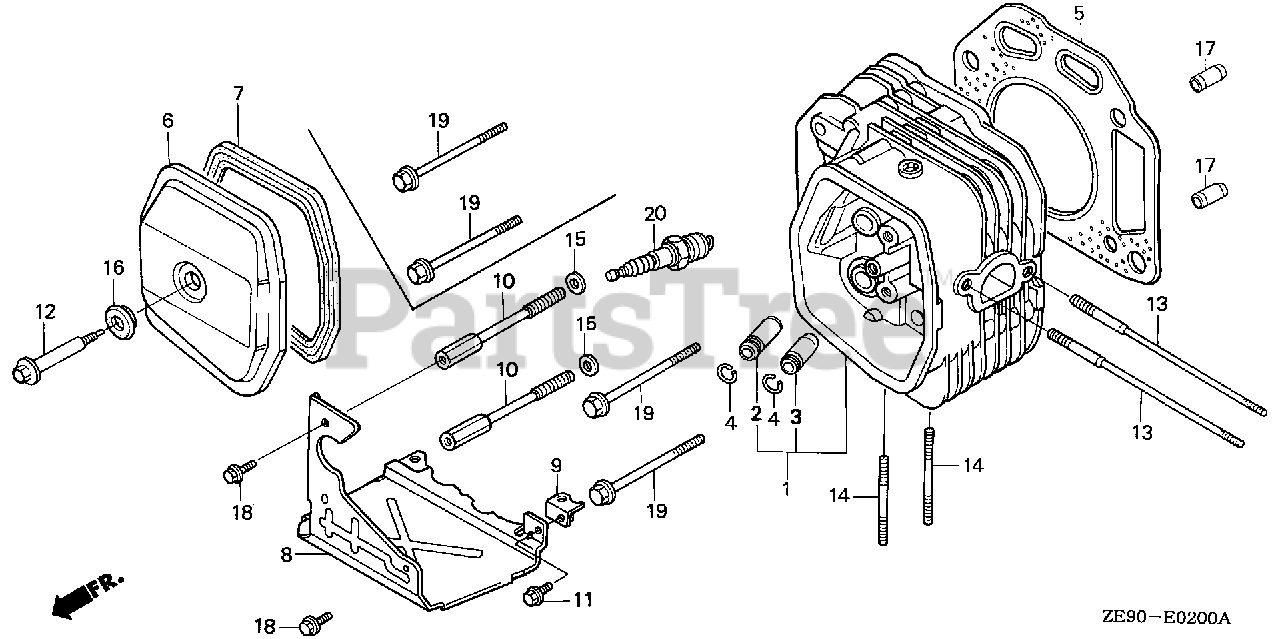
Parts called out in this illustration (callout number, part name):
1	CYLINDER HEAD
2	GUIDE, VALVE (OVER SIZE)
3	GUIDE, EX. VALVE (OVER SIZE)
4	CLIP, VALVE GUIDE
5	GASKET, CYLINDER HEAD
6	COVER, HEAD
7	GASKET, HEAD COVER
8	COVER (LOWER)
9	STAY, COVER (LOWER)
10	BOLT, SPECIAL HEAD COVER
11	BOLT, FLANGE (6X12) (CT200)
12	BOLT, HEAD COVER
13	BOLT, STUD (8X131.5)
14	BOLT, STUD (8X47)
15	WASHER, SPECIAL (11X21X2.3)
16	WASHER, HEAD COVER
17	PIN, DOWEL (12X20)
18	BOLT, FLANGE (6X12)
19	BOLT, FLANGE (10X80)
20	SPARK PLUG (BPR5ES) (NGK)
20	SPARK PLUG (W16EPR-U) (DENSO)
